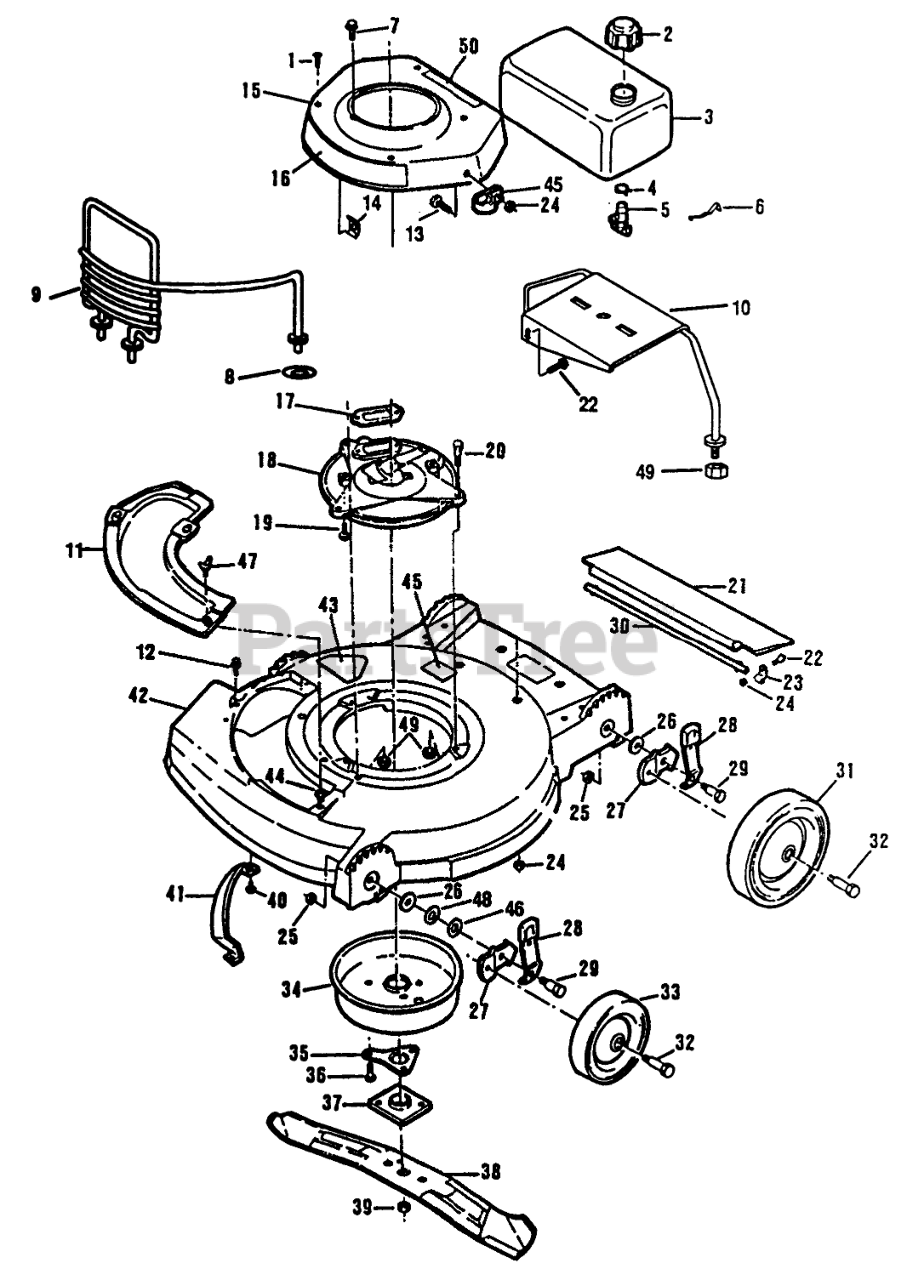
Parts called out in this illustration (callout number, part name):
1	SCREW S
2	FUEL CAP & INSERT
3	Gas Tank
4	CLAMP - HOSE S
5	VALVE&SCREEN SM
6	SPRING
7	SCREW SEMS SM
8	Washer
9	Engine Guard
10	Bracket-Tank
11	CoverPlate
12	Bolt
13	Screw
14	PUSHNUT F
15	SHROUD AY B S
16	APPLIQUE S
17	Gasket
18	PLATE F
19	SCREW V
20	SCREW-HH
21	T/SHIELD GEAUGA
22	Screw
23	CLAMP ROD KMC
24	LOCKNUT E
26	WASHER
27	Bracket
28	SPRING ARM ASM
30	ROD 21" ADVANCE
31	WHEEL/TIRE ASM
33	WHEEL AND TIRE ASM
34	MUFFLER COVER F
35	SUPPORT F
36	SCREW
37	PLATE AND COLLAR ASM
38	21" Blade
39	NUT-BLADE
40	Screw
41	BAR-TOE
42	Housing Assembly
43	Decal
44	Grommet
45	CLAMP F
46	WASHER
47	WING SCREW LAWRE
48	WASHER
49	NUT-LOCK F
50	DECAL S
